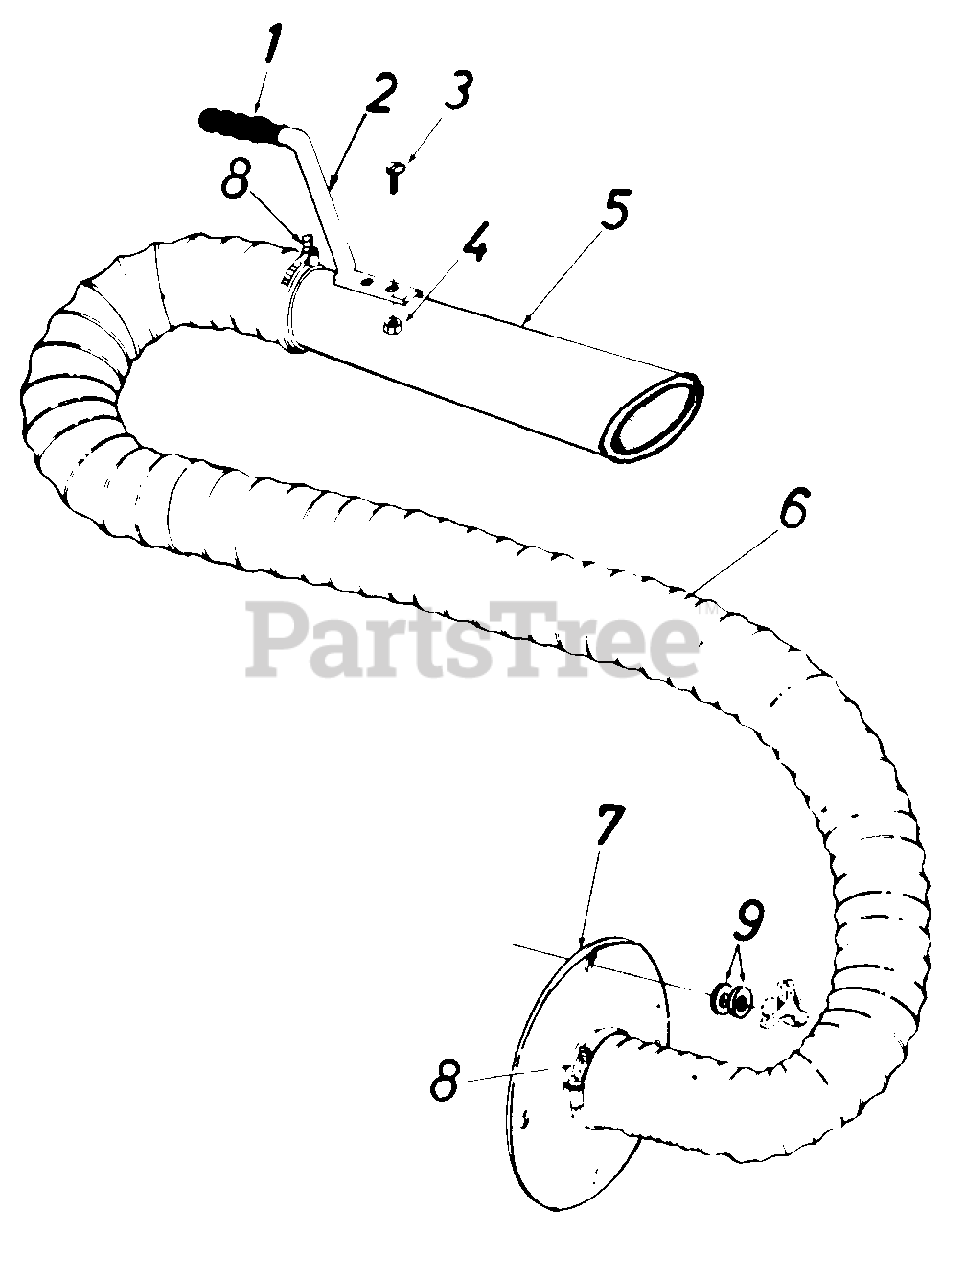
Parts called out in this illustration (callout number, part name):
1	Handle Grip
2	Handle
3	Truss Sems Scr. 1024 x 1/2 ' Lg.
4	Hex Nut 10-24 Thd.
5	Hose Nozzle
6	Flexible Hose 4" Dia. x 10' Lg.
9	Flat Washer .34 I.D. x 1.12 O.D.
